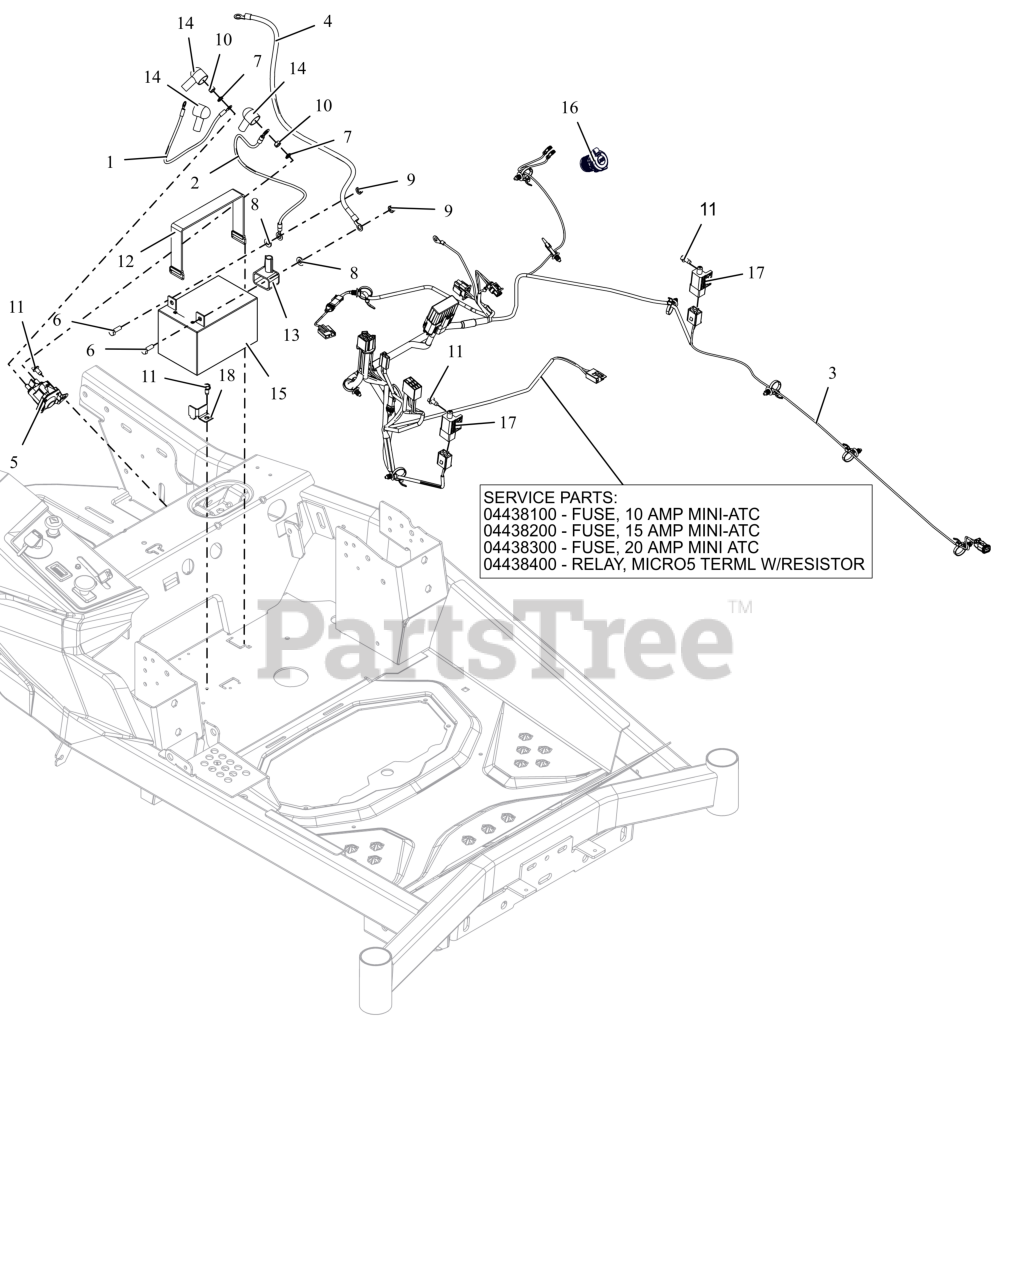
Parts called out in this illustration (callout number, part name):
1	CABLE,POS W/2 1/4 RING 15.0 LG
2	CABLE,POS W/2 1/4 RING 18.5 LG
3	HARNESS- MAIN- IKON23
3	FUSE,10 AMP MINI-ATC
3	Fuse, 15 AMP MINI-ATC
3	FUSE,20 AMP MINI ATC
3	RELAY,MICRO5 TERML W/RESISTOR
4	CABLE-NEGATIVE BATTERY 24.00"
5	SOLENOID, STARTER (SEALED)
6	BLT, HEX .25-20X.75 G5 ZCC
7	WSHR,LK-EXT.262X.502X.026 ZCC
8	WSHR,FLT .281X.625X.065 ZCC
9	NUT-KEPS .250-20 ZCC
10	NUT-STD M6-1.0 ZCC
11	SCR-TAP .25-20X.50 HWH ZCC
12	STRAP- RUBBER
13	INSULATOR
14	BOOT, EYELET TERMINAL
15	BATTERY, 12V 12A -190CCA
16	USB, DUAL PORT USB-C, 12V BLK
17	SWITCH-BRAKE NO/NO-POST & HOLE
18	RETAINER, BATTERY CORNER (BLACK)
